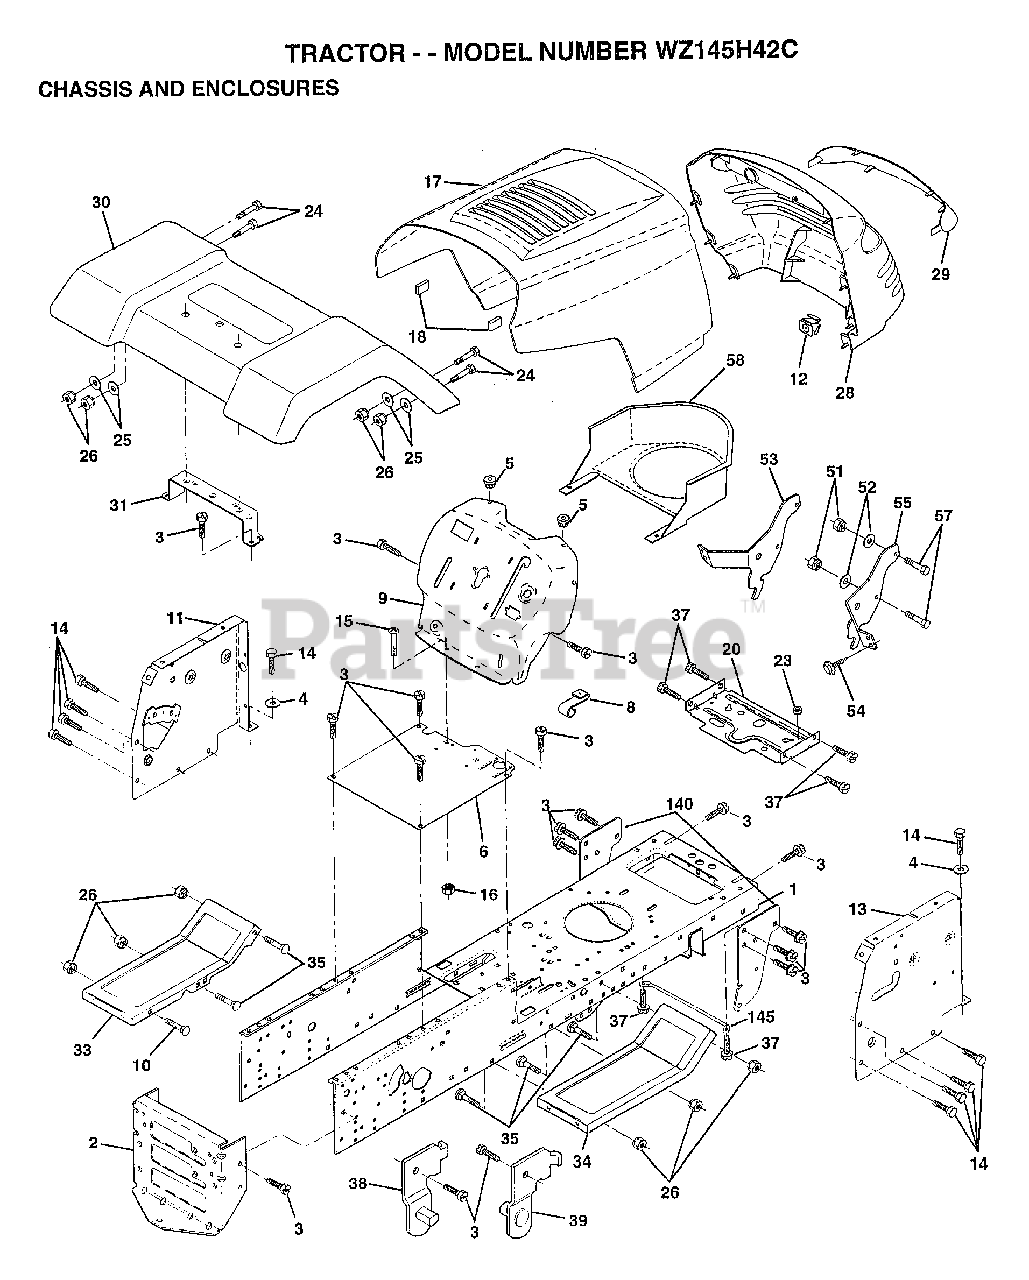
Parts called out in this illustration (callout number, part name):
1	CHASSIS.STAMPING
3	SCREW
4	WASHER
5	BUMPER-HOOD/DASH
6	SADDLE
8	CLIP.RETAINER
9	DASH SILKSCREEN
11	"PANEL-DASH,LH"
12	CLIP.TINNERMAN
14	SCREW LT
15	SCREW
17	HOOD.STEEL.ASSY
20	"PLATE-MTG,BATT/FU"
24	BOLT
25	WASHER
26	NUT
28	GRILLE-MS428
29	LENS.GRILLE.PRIVATE LABEL
30	FENDER.LT.W/SHIFT
31	BRKT FENDER
33	FOOTREST.LH.LT/GT
34	FOOTREST.RH.LT/GT
35	BOLT
37	SCREW LT
38	BRACKET ASM LH
39	BRACKET ASM RH
51	NUT
52	WASHER
53	BRACKET.GRILLE.LH
54	SCREW.HEX.WS.HD
55	BRACKET.GRILLE.RH
58	AIR DUCT
140	BRKT SUSPENSION
145	"ROD POVOT,CHASSIS"
